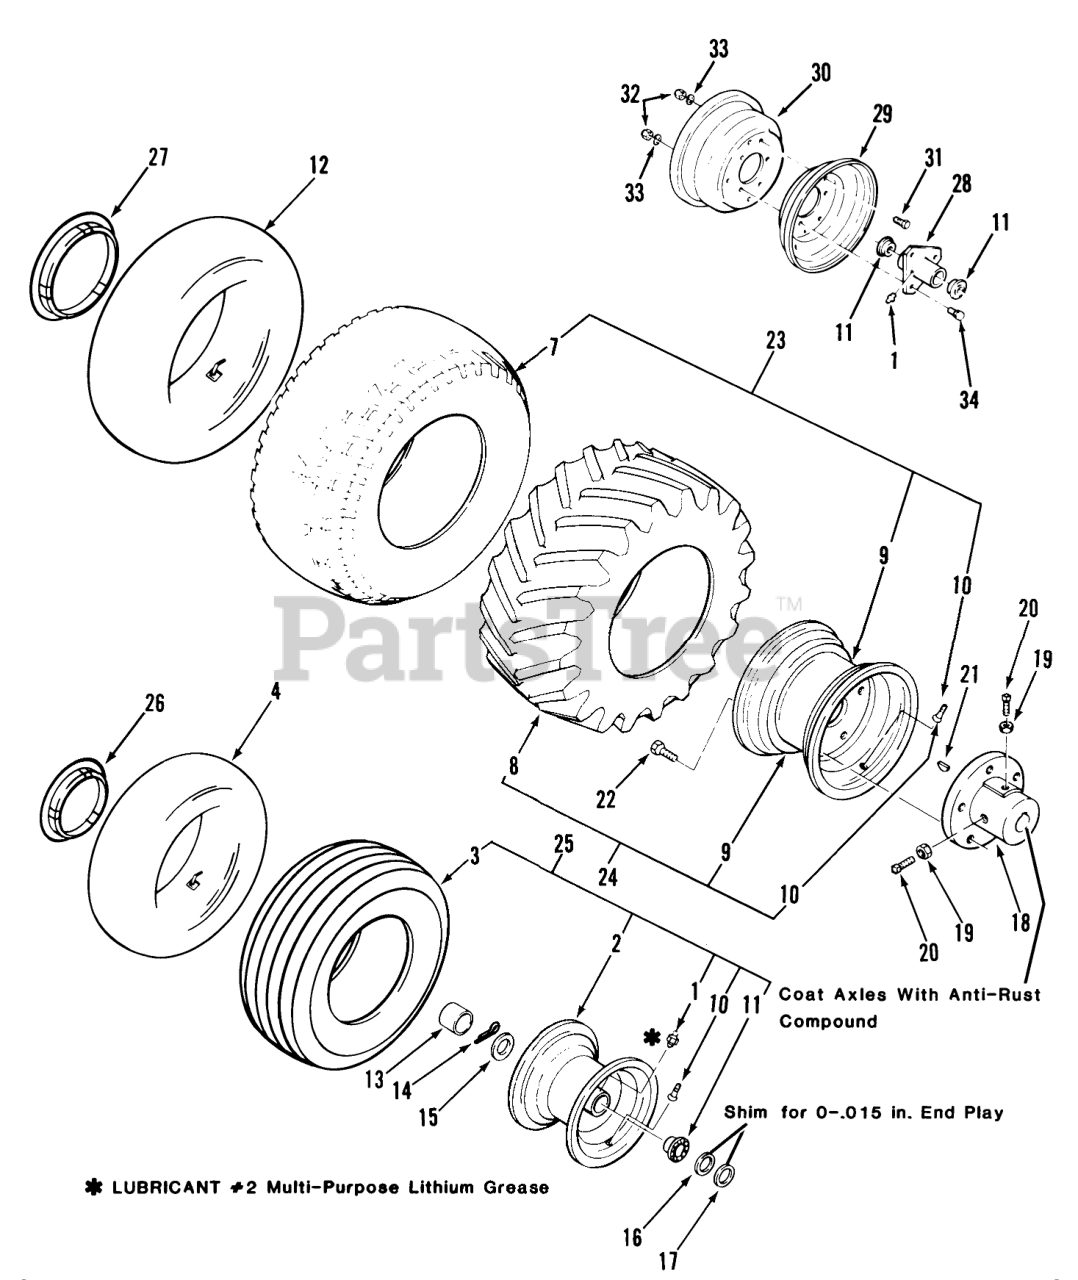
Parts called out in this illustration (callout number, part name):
1	ZERK-GREASE
2	Front Wheel (includes Item 1, 11) 312-A
2	Front Wheel (includes Item 1, 10, 11) 308-8, 310-8
3	TIRE15 X 6.00-6
3	Front Tire 15x6.00-6 Rib Tread 308-8
7	TIRE 22 X 9.00-12
7	TIRE 22 X 7.50-12
8	Tire-Cleat, Rear
9	WHEEL
10	VALVE
11	BEARING-WHEEL
12	INNER TUBE
13	HUB CAP-FLAT BLACK
14	COTTER PIN-4
15	WASHER-WHEEL
16	WASHER
17	WASHER-SHIM
18	Hub Rear
19	Nut
20	Screw-Set
21	KEY-WOODRUFF
22	Lug Nut
23	Rear Wheel & Tire Assy 312-A
23	Rear Wheel & Tire Assy 308
24	ASSY WHEEL & TIRE
25	ASSY WHEEL & TIRE
25	Front Wheel & Tire Assy 308-8
26	HUB CAP 6 IN.
27	HUB CAP 12 IN.
28	Hub (chrome) 420-LSE Only
29	Inside Rim (chrome) 420-LSE Only
30	Outside Rim (chrome) 420-LSE Only
31	Bolt 3/8-24 x 5/8 420-LSE Only
32	CHROME LUG NUT
33	LOCKWASHER
34	Ser. Hex Bolt 3/8-24 x 3/4 420-LSE Only
